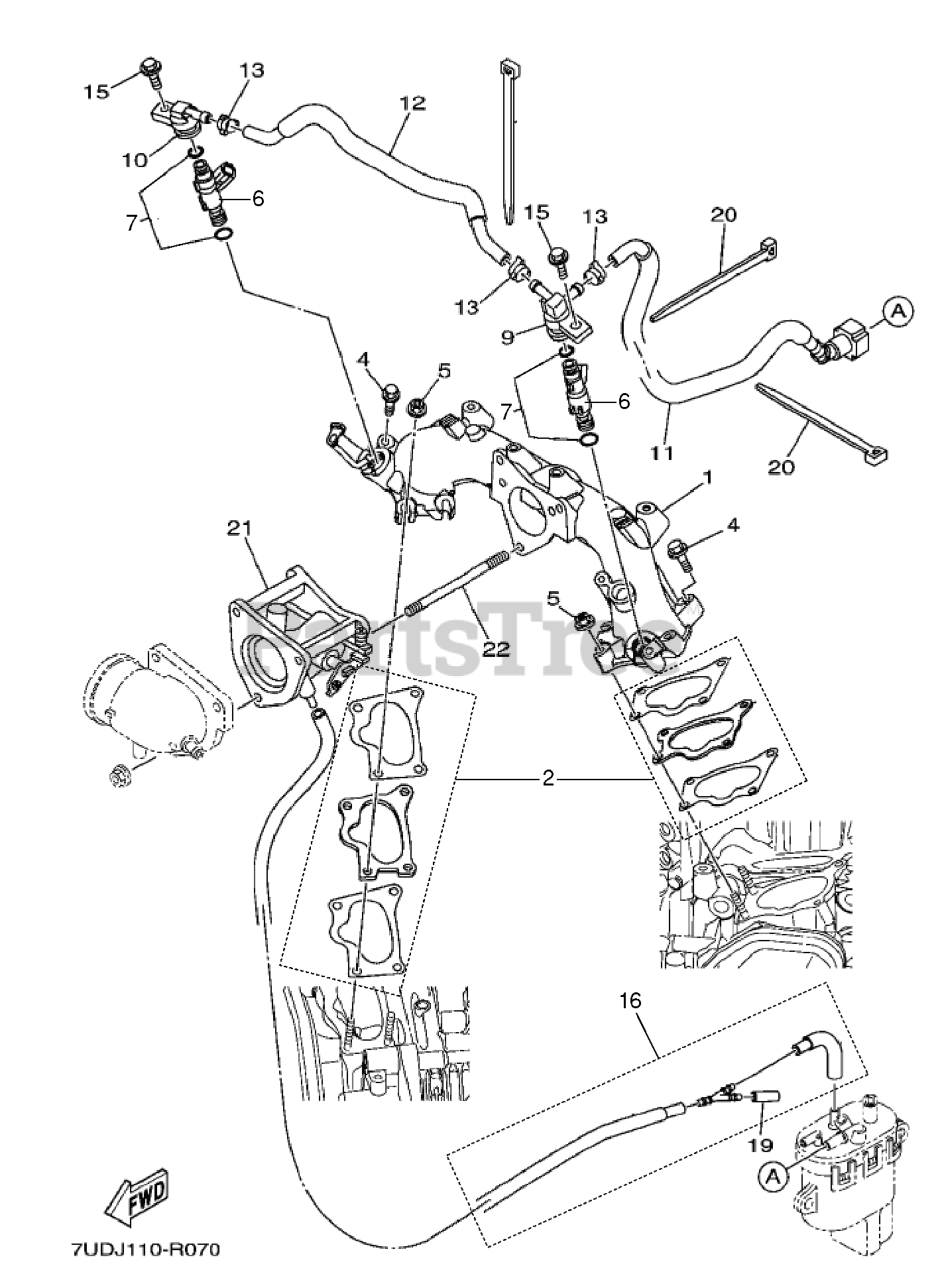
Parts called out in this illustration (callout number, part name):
1	MANIFOLD YAMAHA PN: 7UD-E3585
2	GASKET KIT INTAKE
4	BOLT YAMAHA PN: 95802-06035
5	NUT YAMAHA PN: 95702-06500
6	INJECTOR YAMAHA PN: 7UD-E3761
7	O-RING INJECTOR O-RING KIT
9	PIPE YAMAHA PN: 7UD-E3938-00
10	PIPE INLET 2 YAMAHA PN: 7UD-E3
11	PIPE FUEL INJECTION 1 YAMAHA P
12	PIPE FUEL INJECTION 2 YAMAHA P
15	BOLT YAMAHA PN: 95802-06016
16	HOSE KIT INTAKE HOSE KIT
19	CAP JOINT YAMAHA PN: 7UD-E3587
20	CLAMP YAMAHA PN: 90464-35820
21	THROTTLE ASSY YAMAHA PN: 7UD-
22	BOLT YAMAHA PN: 90116-06307
